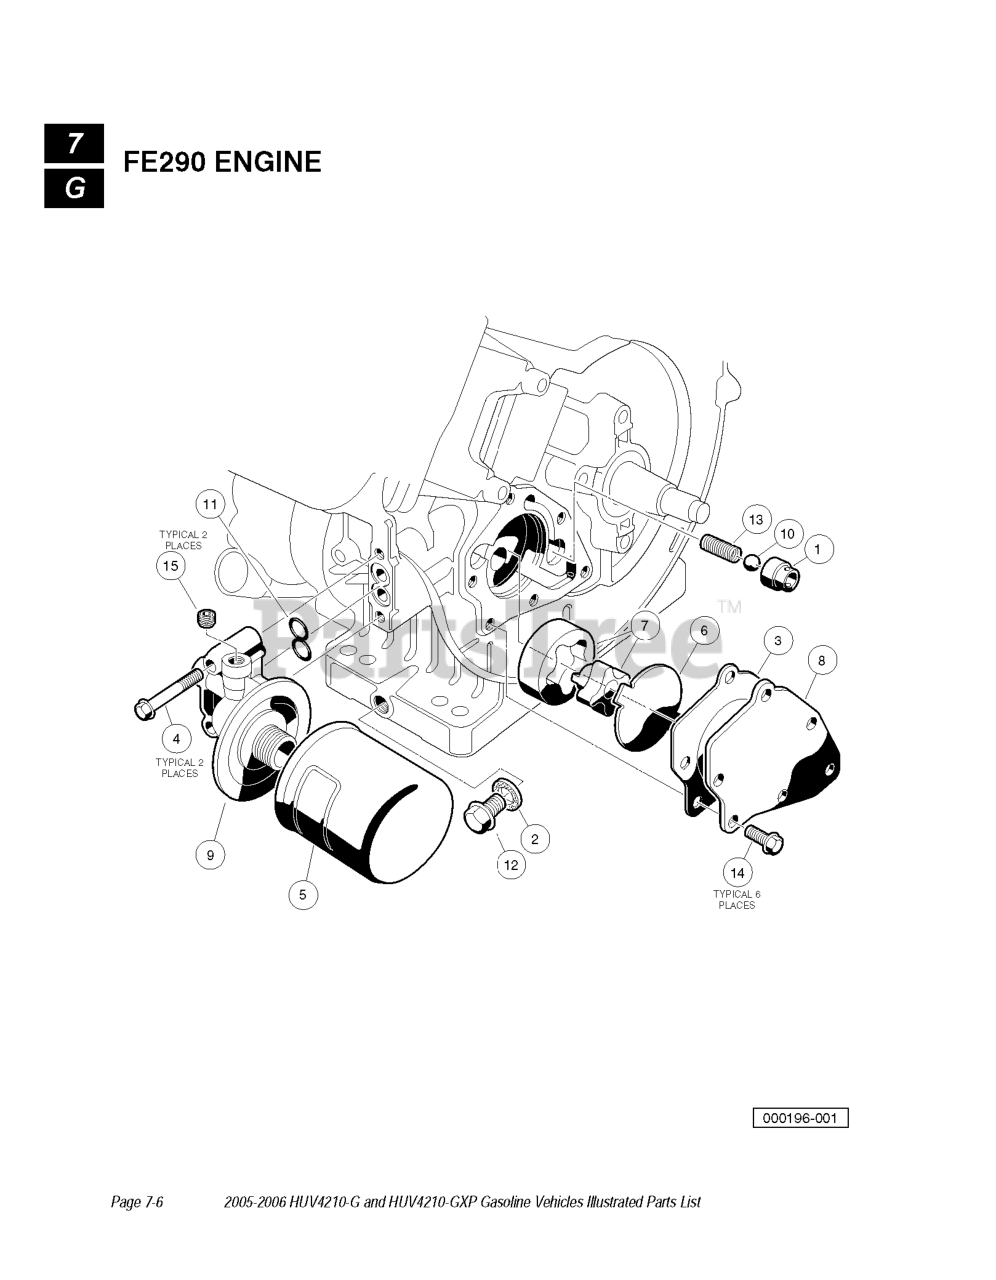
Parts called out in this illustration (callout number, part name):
1	SEAT, VALUE OIL PRESS RELIEF
2	GASKET, DRAIN PLUG
3	GASKET, OIL PUMP
4	BOLT, FLANGED
5	FILTER, OIL
6	PLATE - OIL - PUMP
7	OIL PUMP AND ROTOR
8	COVER, PUMP
9	BRACKET - OIL FILTER MOUNT
10	BALL, STEEL, PRESS, RELIEF
12	PLUG, DRAIN FE290D
14	BOLT - FLANGED SMALL
